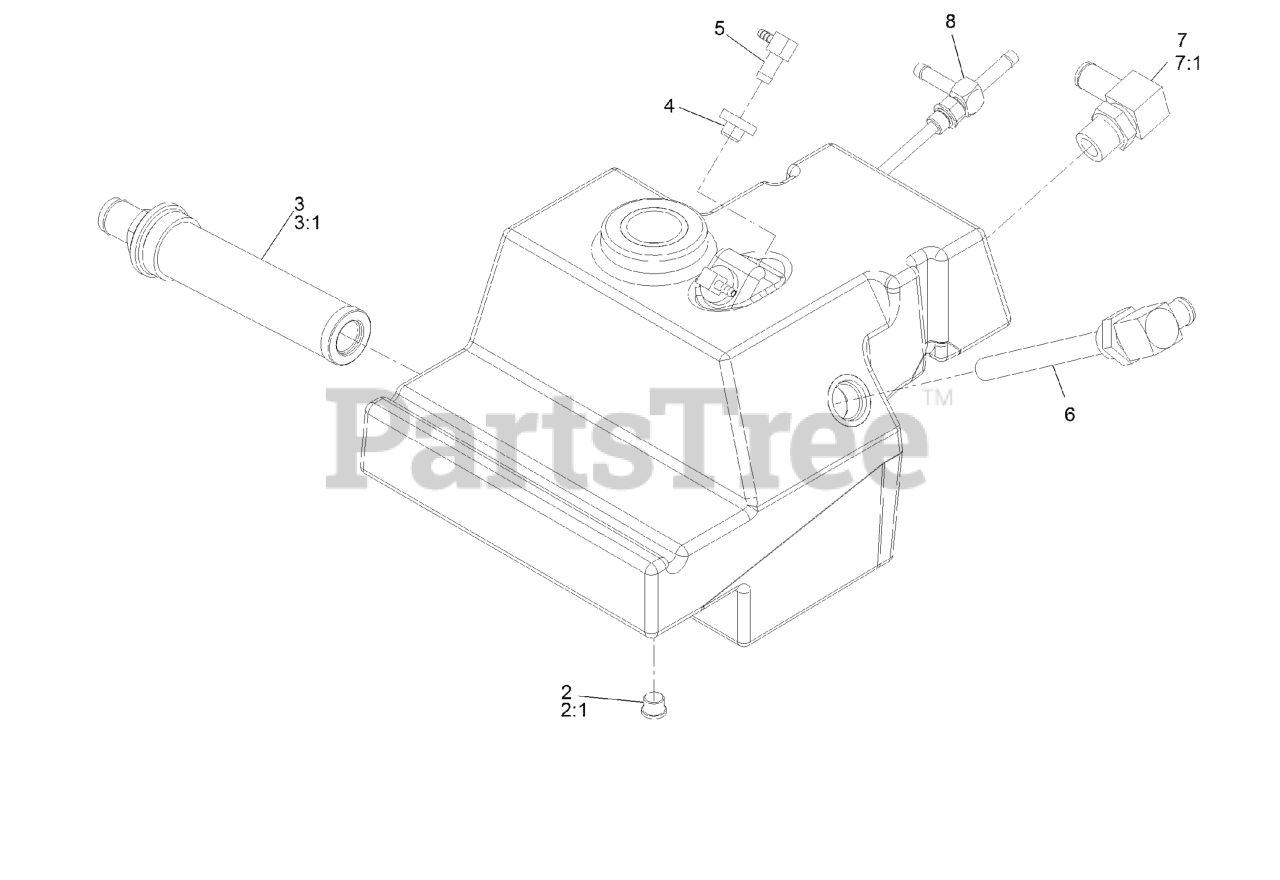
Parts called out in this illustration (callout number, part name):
2	PLUG-HEX, HOLLOW
2:1	O-RING
3	TANK STRAINER ASM
4	BUSHING
5	FITTING-ELBOW, 90 DEG
6	Fitting-Standpipe
7	FITTING-ELBOW, 90
7:1	O-RING
8	FITTING-TEE, DROP TUBE
